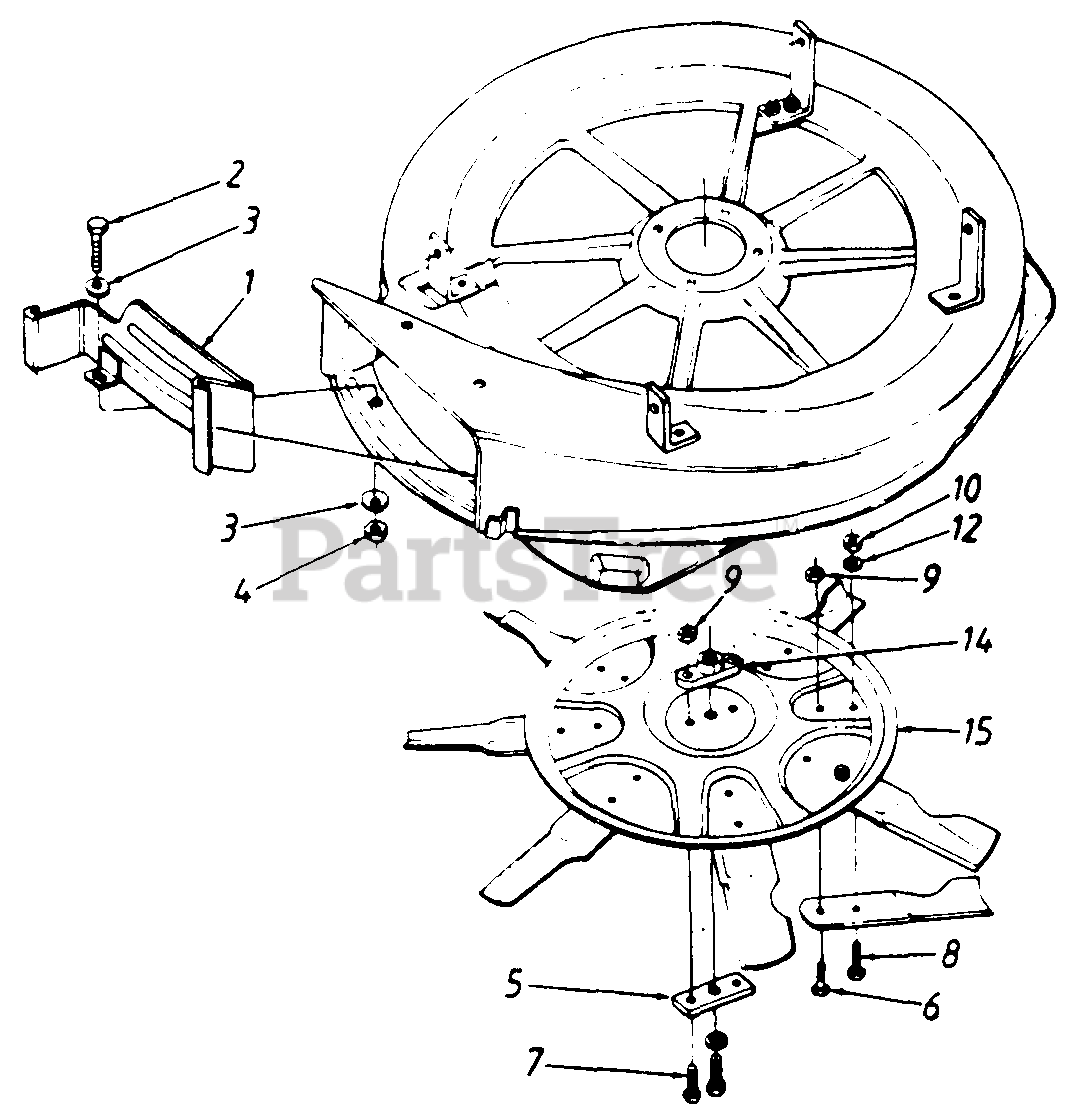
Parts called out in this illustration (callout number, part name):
1	Mulching Baffle Ass'y.
2	Hex Bolt 5/16-18 x .5"
3	Bell-Wash. .325" I.D.
4	Hex L-Nut 5/16-18 Thd.
7	Hex Bolt 5/16-24 x 1.25" Lg, (Gr. 5)
8	Hex Bolt 3/8-24 x .88" Lg.
9	Hex L-Nut 5/16-24 Thd.
10	Hex L-Nut 3/8-24 Thd. (Gr. 5)
12	Fl-Wash..406" I.D. x .75"
14	Blade Adapter
15	30" Mulching Blade Disc
